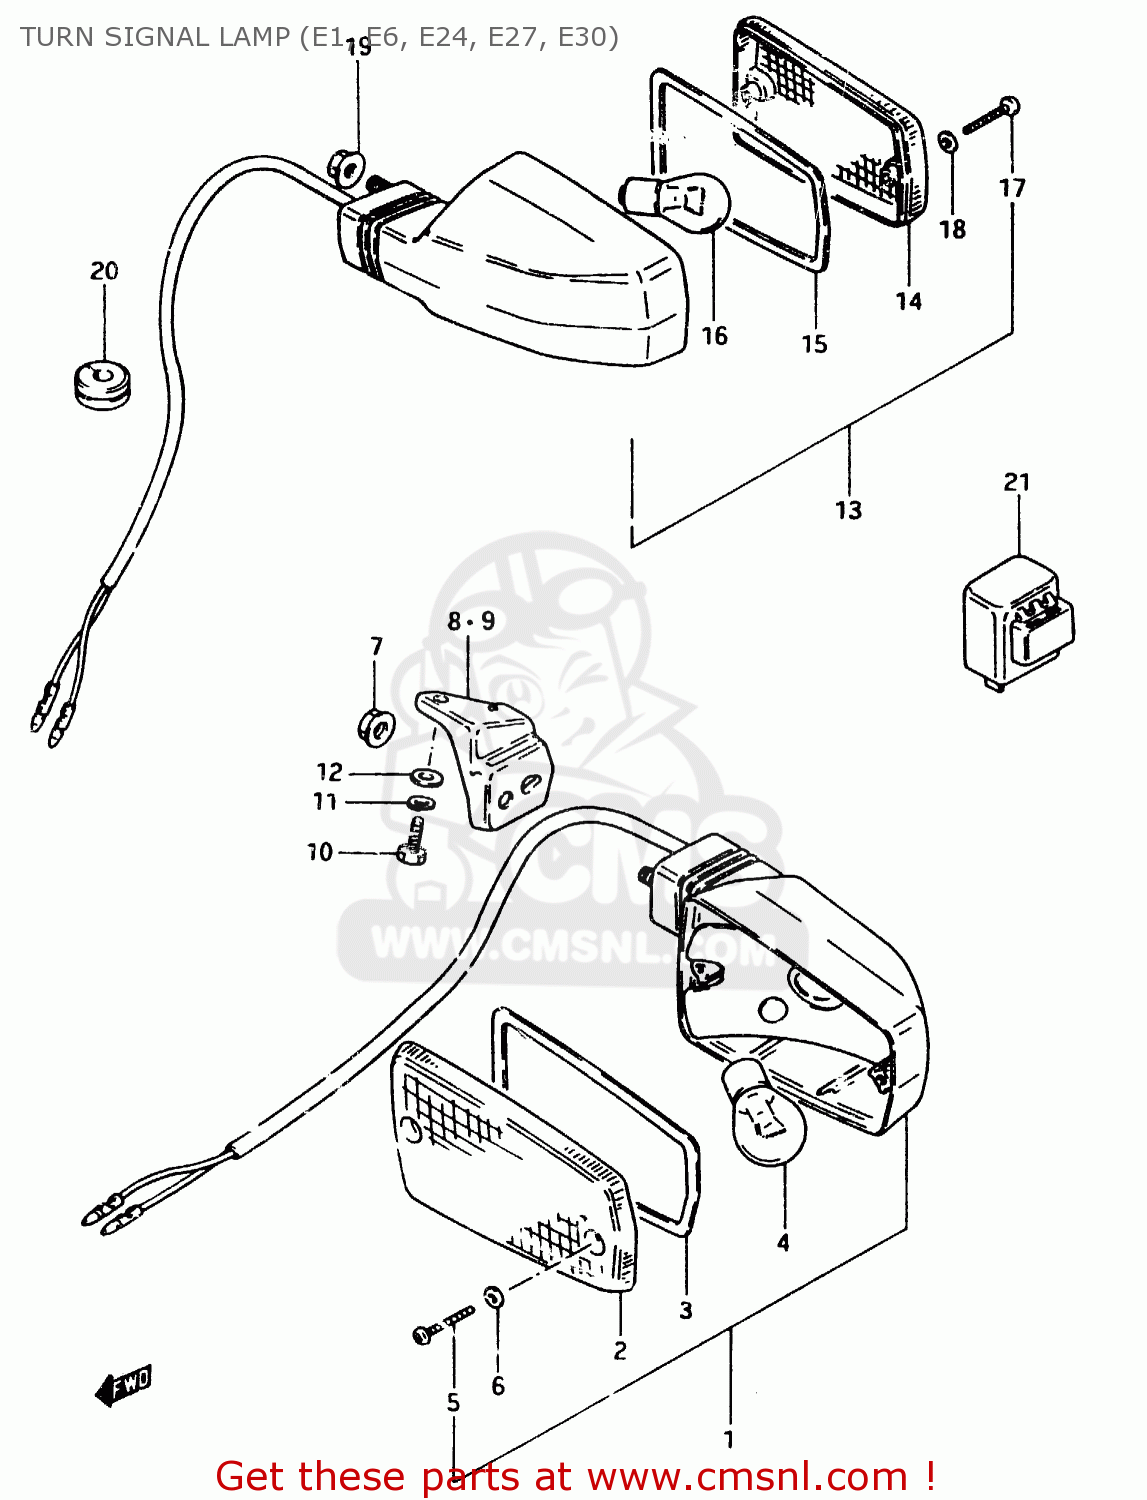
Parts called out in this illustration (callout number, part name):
1	LAMP ASSY, FRONT TURN SIGNAL
2	LENS
3	GASKET (NAS)
4	BULB(12V23W,STANLEY,A4577A)
5	SCREW
6	GASKET (NAS)
7	NUT
8	BRACKET,FRONT TURN SIGNAL
9	BRACKET,FRONT TURN SIGNAL
10	BOLT
11	LOCK WASHER
12	WASHER,8.5X16X
13	LAMP ASSY REAR
14	LENS
15	GASKET (NAS)
16	BULB(12V23W,STANLEY,A4577A)
17	SCREW
18	GASKET (NAS)
19	NUT
20	GROMMET
21	RELAY ASSEMBLY,TURN SIGNAL
